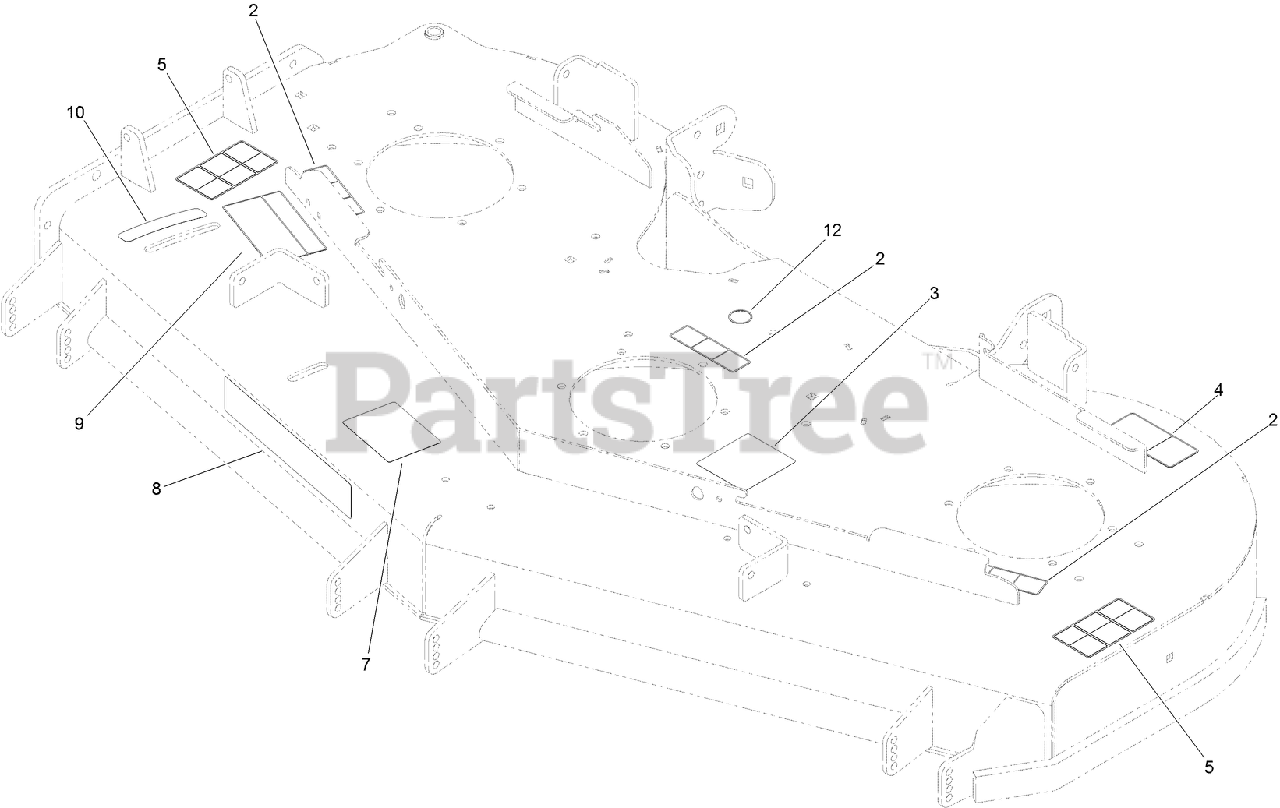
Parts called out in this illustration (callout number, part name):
2	DECAL-MISSING, COVER
3	DECAL-ROUTING, DECK BELT
4	DECAL-TORQUE, BLADE BOLT
5	DECAL-DANGER
7	DECAL-SCALP, ANTI
9	DECAL-ADJUSTMENT, BAFFLE
10	DECAL-SETTING, BAFFLE
12	DECAL-GREASE
